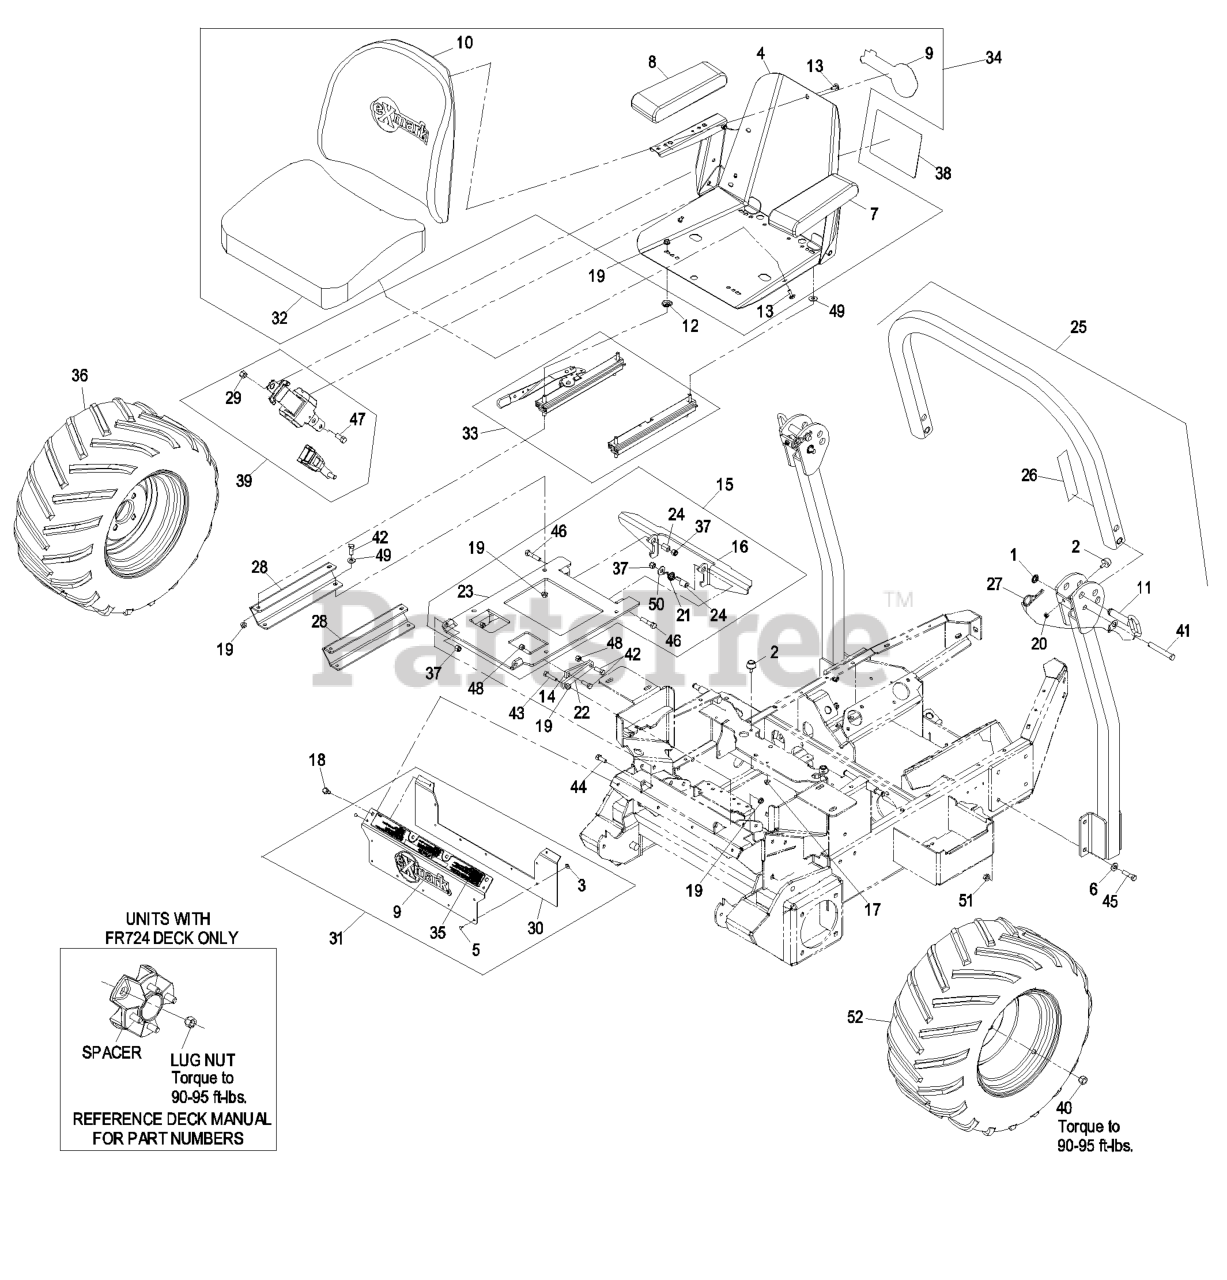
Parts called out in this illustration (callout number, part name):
1	NUT-PUSH
2	BUMPER-RUBBER
3	WASHER-FLAT
4	FRAME-SEAT
5	RIVET-POP
6	WASHER-BELLEVILLE
7	CUSHION,ARMREST LH
8	CUSHION,ARMREST RH
9	DECAL,EXMARK LOGO
10	CUSHION,SEAT BACK
11	PIN-FOLD, ROPS
12	SPACER-TRACK
13	BOLT-SEAT
14	LINK-STOP, SEAT
15	ASM, SEAT FRAME FMZ
18	SCREW-HWH, THREAD CUT
20	NUT-LOCK, NI
22	LINK,FMZ LWR SEAT STOP (P
24	BUSHING-LEVER, LIFT
25	KIT,ROPS FMZ
26	DECAL-WARNING, FOLDING RO
27	HAIRPIN
28	SUPPORT, ANGLED SEAT
29	NUT-LOCK
30	Skirt, Rubber
31	ASM,FRONT CONSOLE W/ DECA
35	DECAL,TOP CONSOLE
36	ASM,WHEEL AND TIRE LUG RH
37	NUT-LOCK, NI
38	DECAL,FR SERVICE AID
39	RETRACTABLE SEATBELT KIT
40	NUT-LUG
41	PIN-CLEVIS
42	SCREW-HH
43	SCREW-HH
44	SCREW-HH
45	SCREW-HH
46	SCREW-HH
47	SCREW-HH
48	NUT-LOCK, NI
49	WASHER-FLAT
50	WASHER-FLAT
51	NUT-HHF, WHIZ
52	ASM,WHEEL AND TIRE LUG LH
